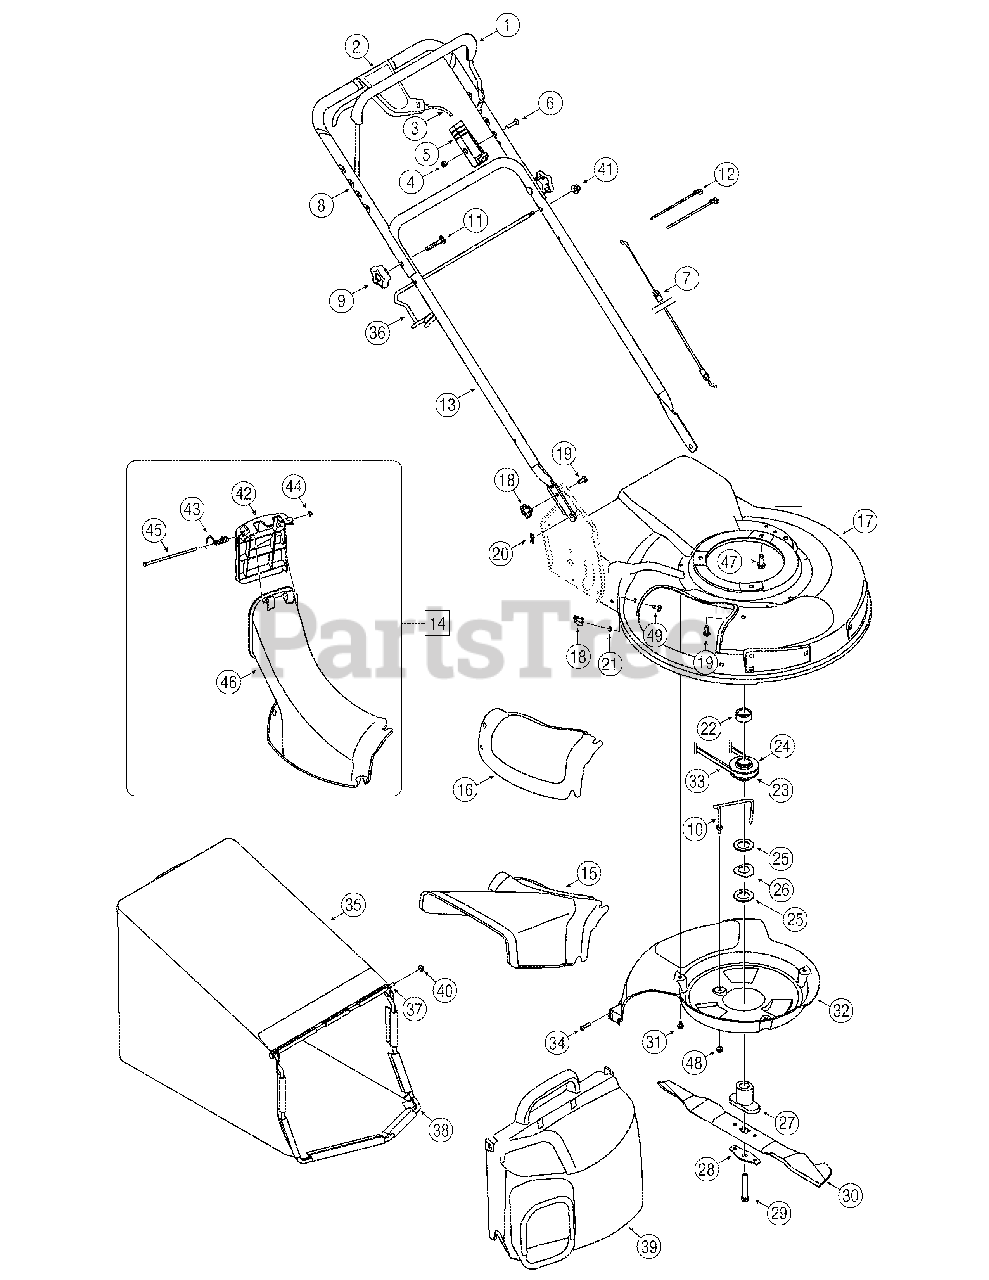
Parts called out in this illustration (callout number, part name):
1	Deluxe Control Handle
2	Control Lever Assembly
3	Drive Cable 51"
4	Top Lock Nut 1/4-20
5	Control Housing
6	Oval C-Sunk Screw
7	Control Cable 47"
9	Star Knob
10	Belt Keeper
11	Carriage Bolt 5/16-18 x 2.
12	Cable Tie
14	Chute Assembly
15	Side-Discharge Chute
16	Mulch Cover
19	Carriage Bolt 1/4-20 x .
20	Cotter Pin
21	Push Nut .25 x ID x .
22	Sleeve Spacer 25mm x 1.375 x
23	Half Pulley: Key 25mm x
24	Half Pulley: Upper 25mm
25	Flat Washer 1.00 x 1.75
26	Spring Washer 1.005 x 1.825 x
27	Blade Adapter Kit
28	Blade Bell Support
29	Hex Bolt 3/8-24 x 2.5
30	21" Mulching Blade
31	Screw 1/4-20 x 3.75
32	Baffle
33	Belt 3/8 x 39.24
34	HL Screw #12-16 x 1.00
35	Grass Catcher Assembly
37	Pivot Rod
39	Grass bag Cover
41	Hex Nut 5/16-18
42	Chute Door
43	Torsion Spring
45	Pivot Rod
46	Discharge Chute
47	Sems Screw 3/8-16 x 1.00
48	Flange Lock Nut, 14-20
49	Carriage Bolt 1/4-20 x .62
